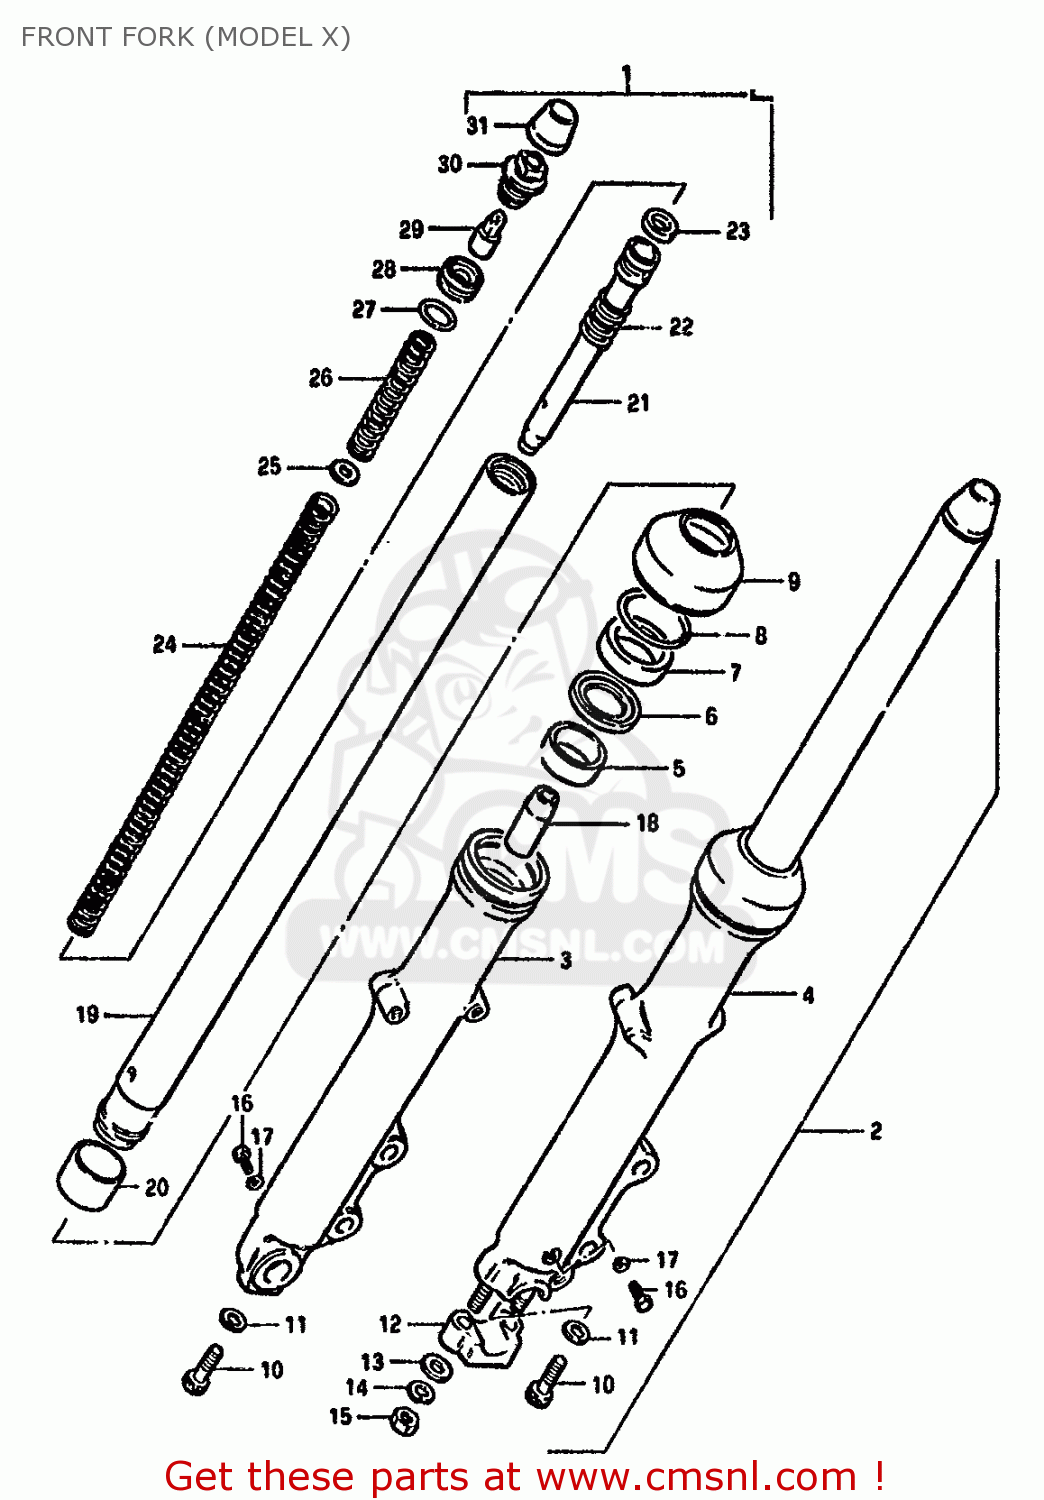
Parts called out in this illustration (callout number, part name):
1	DAMPER ASSY,RH
2	DAMPER ASSY,LH
3	TUBE,FORK,OUTER,RIGHT
4	TUBE,OUTER,LEFT
5	BUSH,GUIDE
6	SPACER,SEAL
7	OIL SEAL,FRONT FORK
8	CIRCLIP,FORK OIL SEAL
9	BOOT
10	BOLT(8X27)
11	GASKET (NAS)
12	HOLDER,AXLE
13	WASHER
14	LOCK WASHER
15	NUT
16	BOLT(6X8)
17	GASKET,DRAIN,PLUG (NAS)
18	PIECE,OIL LOCK
19	INNER TUBE
20	PISTON
21	CYLINDER
22	SPRING,FORK REBOUND
23	RING
24	SPRING B
25	WASHER,SPRING
26	SPRING (A)
27	O-RING
28	SEAT, SPRING
29	ADJUSTER, SPRING
30	BOLT
31	CAP
